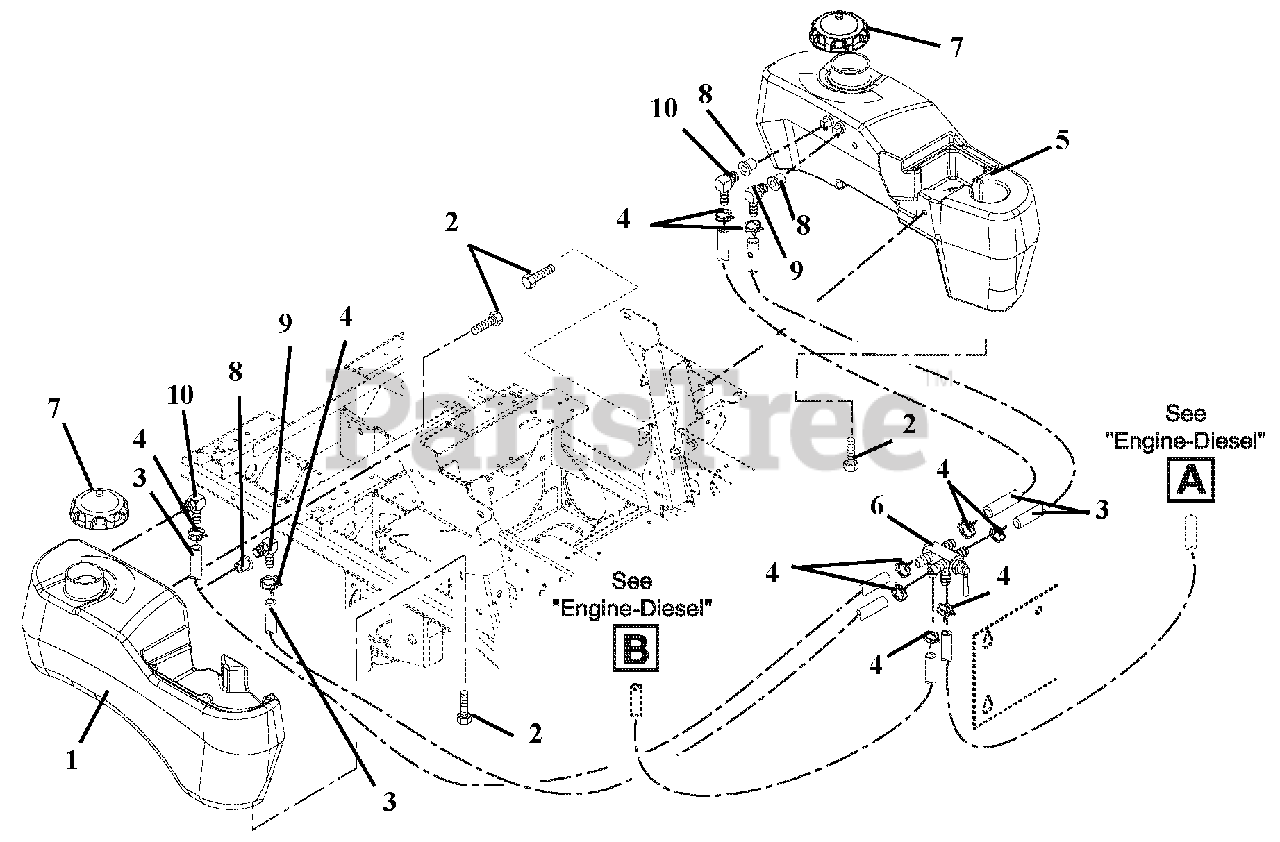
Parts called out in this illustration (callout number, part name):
1	Tank, Fuel-Right Hand
2	Bolt, SEMS .31-18 x .62
3	Hose, .31 ID
4	Clamp, Hose Wire .52/.55
5	Tank, Left Hand Fuel (EYE-Q) 200 Series-EFI
6	Valve, Fuel
7	Cap, Fuel
8	Grommet, Orange
9	Fitting, Tank
10	Fitting, Tank
